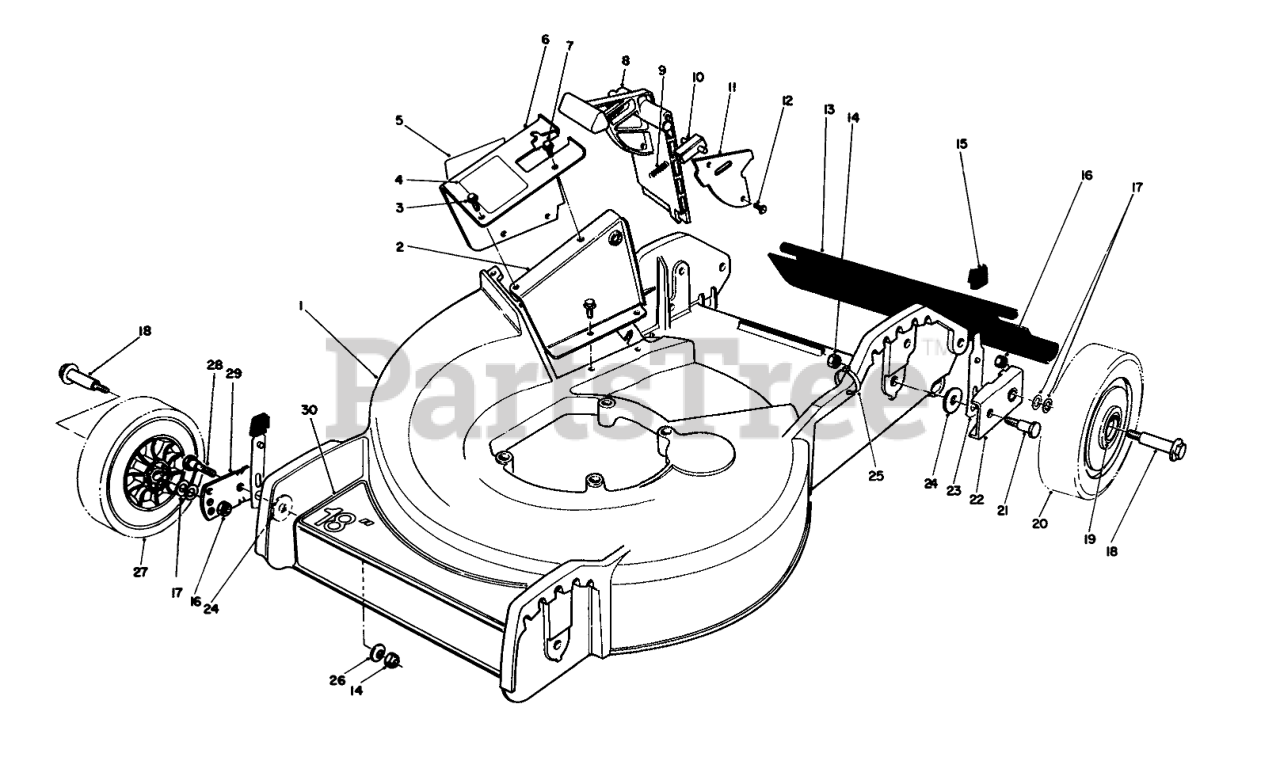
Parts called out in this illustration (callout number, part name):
1	HSG & CARTON
2	Tunnel-Inner
3	SCREW
4	DECAL - DANGER
5	DECAL-DANGER
6	Tunnel-Outer (Incl. Ref. #5)
7	SCREW
8	Door-Mulching
9	SPRING-COMPRESSION, LATCH
10	Door Latch
11	DOOR COVER
13	SHIELD - TRAILING
14	NUT-LOCK, NI
15	KNOB-ARM
16	Nut
17	WASHER
18	BOLT-WHEEL
19	BUSHING
20	Wheel & Tire Assembly (Incl. Ref. #19)
21	PIVOT SCREW
22	PIVOT ARM ASM
23	SPRING ARM ASM
24	PIVOT WASHER
25	TIE-CABLE
26	WASHER-BELLEVILLE
27	Wheel & Tire Assembly (Incl. Ref. #19)
28	5/16-18 PIVOT SCREW
29	PIVOT ARM ASSY
30	DECAL - DECK
